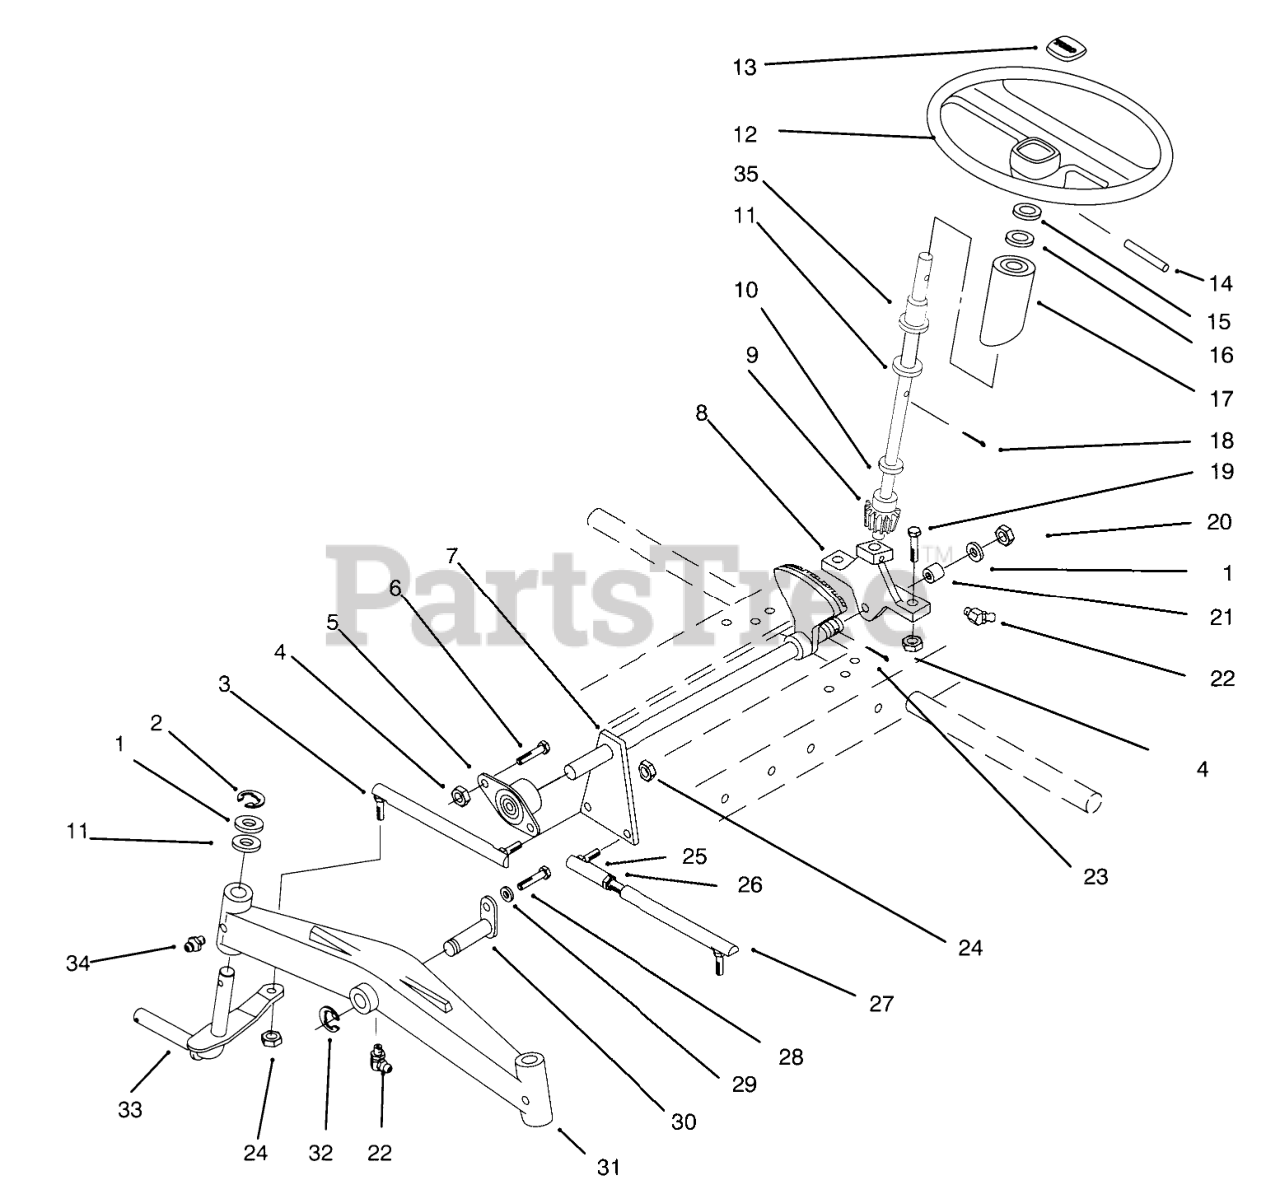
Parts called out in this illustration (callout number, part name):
1	WASHER
2	RING-RETAINING
3	Tie Rod RH
4	NUT-LOCK, NI
5	BEARING-FLANGED
6	SCREW-HH
7	Shaft
8	Support-Steering
9	STEERING SHAFT ASM
10	O-RING
11	WASHER-SHIM
12	Steering Wheel(Incl. Ref. #13)
13	STRG-WHL INSERT TORO
14	PIN-ROLL
15	WASHER-BOWED
16	WASHER-FLAT
17	TUBE-STEERING
18	PIN-COTTER
19	SCREW-HH
20	NUT-HEX, SLOTTED
21	BEARING-BRONZE
22	FITTING-GREASE
23	PIN-COTTER
24	NUT-LOCK
25	BALL-JOINT
26	NUT-HEX
27	Tie Rod Assembly,LH(Incl. Ref.# 25 & 26)
28	SCREW-HH
29	WASHER-LOCK
30	PIN AND PLATE ASM
31	AXLE-FRONT
32	E-RING
33	RH SPINDLE WA
34	FITTING-GREASE
35	BEARING-FLANGED
